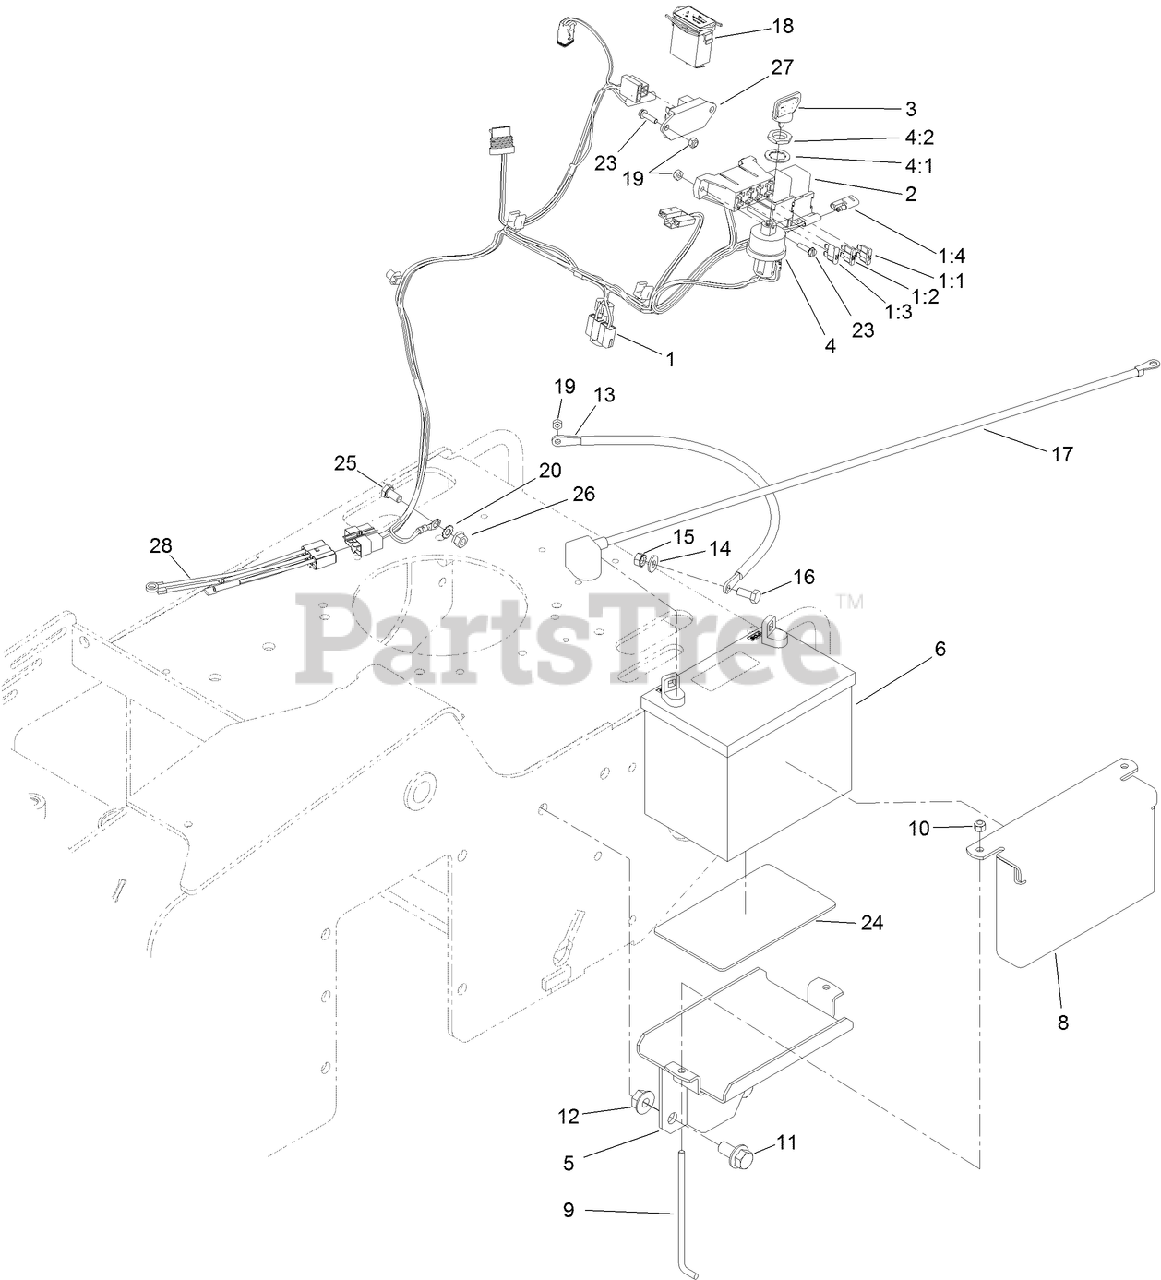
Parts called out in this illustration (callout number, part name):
1	HARNESS-WIRE
1:1	FUSE-BLADE, 30 AMP
1:2	FUSE-BLADE, 25 AMP
1:3	FUSE-BLADE, 20 AMP
1:4	CAP-PLUG
2	RELAY
3	KEY-IGNITION
4	Key Switch ASM
4:1	WASHER-TOOTH, INTERNAL
4:2	NUT-HH
5	TRAY-BATTERY
6	BATTERY-DRY
8	PLATE-HOLD DOWN, BATTERY
9	HOLDOWN-BATTERY
10	NUT-LOCK, NI
11	SCREW-HHF
12	NUT-HHF
13	CABLE-BATTERY, POSITIVE
14	WASHER-FLAT
15	NUT-KEPS
16	SCREW-HH
17	CABLE-BATTERY, BLACK
18	METER-HOUR
19	NUT-LOCK, NI
20	WASHER-LOCK
23	SCREW-HWH
24	PAD-SKID, ANTI
25	SCREW-HH
26	NUT-HF
27	MODULE-DELAY
28	HARNESS
